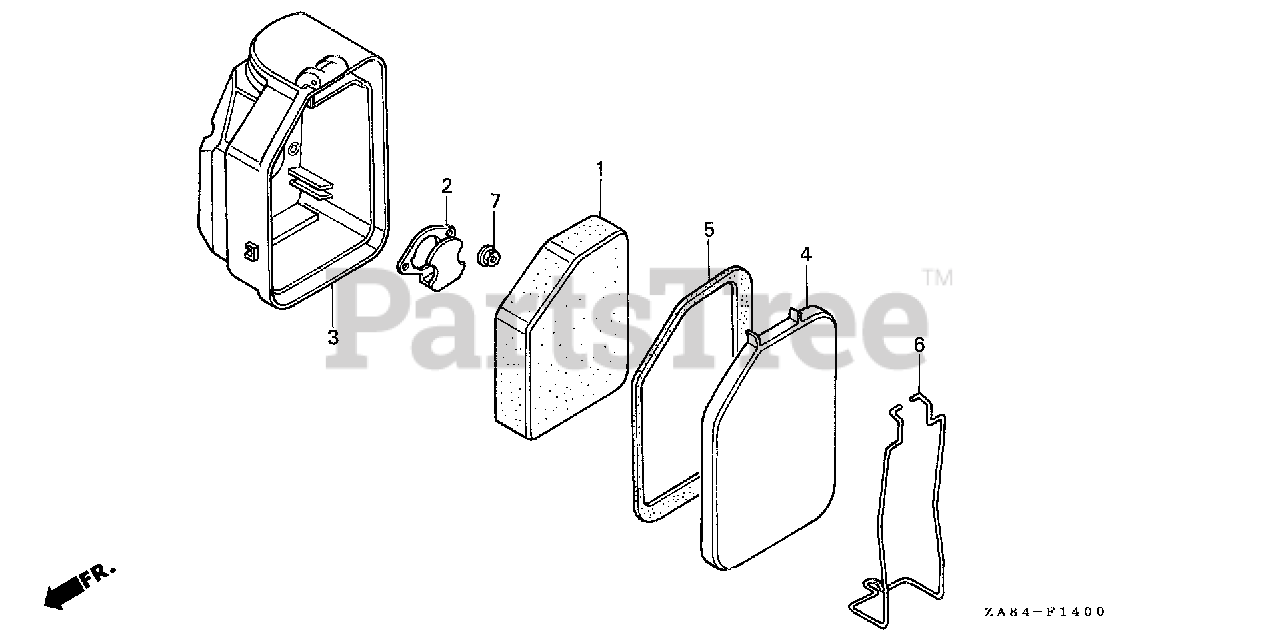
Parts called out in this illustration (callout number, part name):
1	ELEMENT, AIR CLEANER
2	BRACKET, AIR CLEANER
3	CASE SET, AIR CLEANER
3	HOUSING, AIR CLEANER
4	COVER, AIR CLEANER
5	SEAL, AIR CLEANER
6	SPRING, SETTING
7	NUT, FLANGE (6MM)
